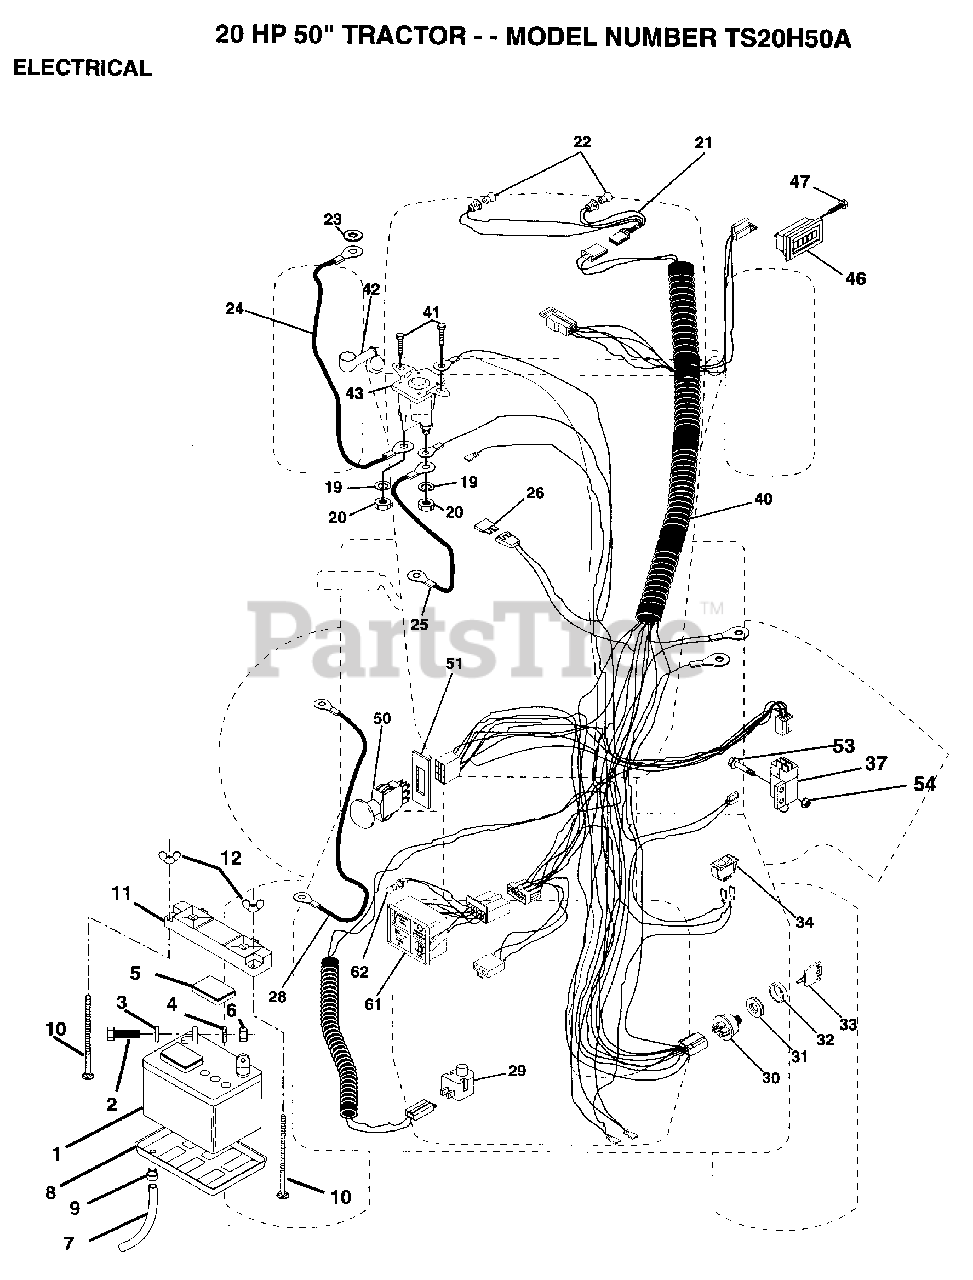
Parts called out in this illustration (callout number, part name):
2	BOLT LT
3	LOCKWASHER
4	WASHER
5	"CAP,BATTERY "
7	"DRAIN TU T, BATT"
8	"TRAY T, BATTERY"
9	HOSE CLAMP T
10	BOLT
20	NUT
22	HEADLAMP BULB
23	LOCKWASHER
24	"CABLE T, BATTERY"
25	CABLE-BATTERY T
26	FUSE HYT
28	CABLE T
29	SWITCH SEAT
32	COVER KEY SWITCH
33	KEY MLD GEN DELTA
34	SWITCH LT
37	SWITCH INTERLOCKT
40	HARNESS IGNITION
41	SCREW
46	HOUR METER T
47	SCREW #10-24 X 1/2
51	RING RETAIN PTO
53	SCREW
54	"NUT,KEPS"
61	LIGHT.PKG.ASM.
62	BULB LIGHT T
